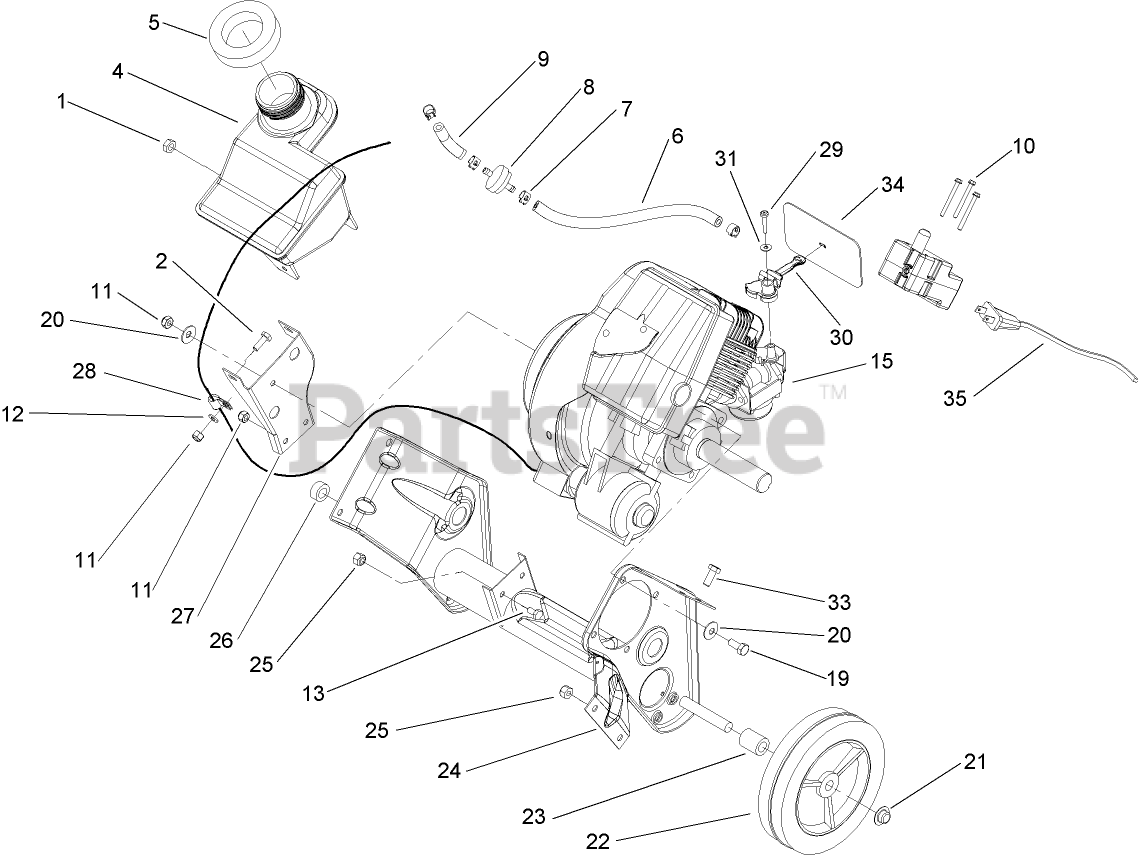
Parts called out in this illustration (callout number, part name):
1	NUT-LOCK, CONE
2	SCREW-HH
4	TANK-GAS
5	SEAL-FOAM
6	LINE-FUEL
7	CLAMP-HOSE
8	FILTER-FUEL
10	SCREW-PLASTITE
11	NUT-LOCK, NI
12	WASHER-FLAT
13	SCREW-HH
19	SCREW-HH
20	WASHER-BELLEVILLE
21	NUT-PUSH
22	WHEEL
23	SPACER-WHEEL
25	NUT-LOCK, NI
26	SPACER-WHEEL
27	BRACKET-SUPPORT, RECOIL
28	CLAMP
29	SCREW-PPH, PLASTITE
30	LEVER-CHOKE
31	WASHER-FLAT
33	SCREW-HH
34	SHIELD-HOLE, CHOKE
35	CORD-ELECTRIC
